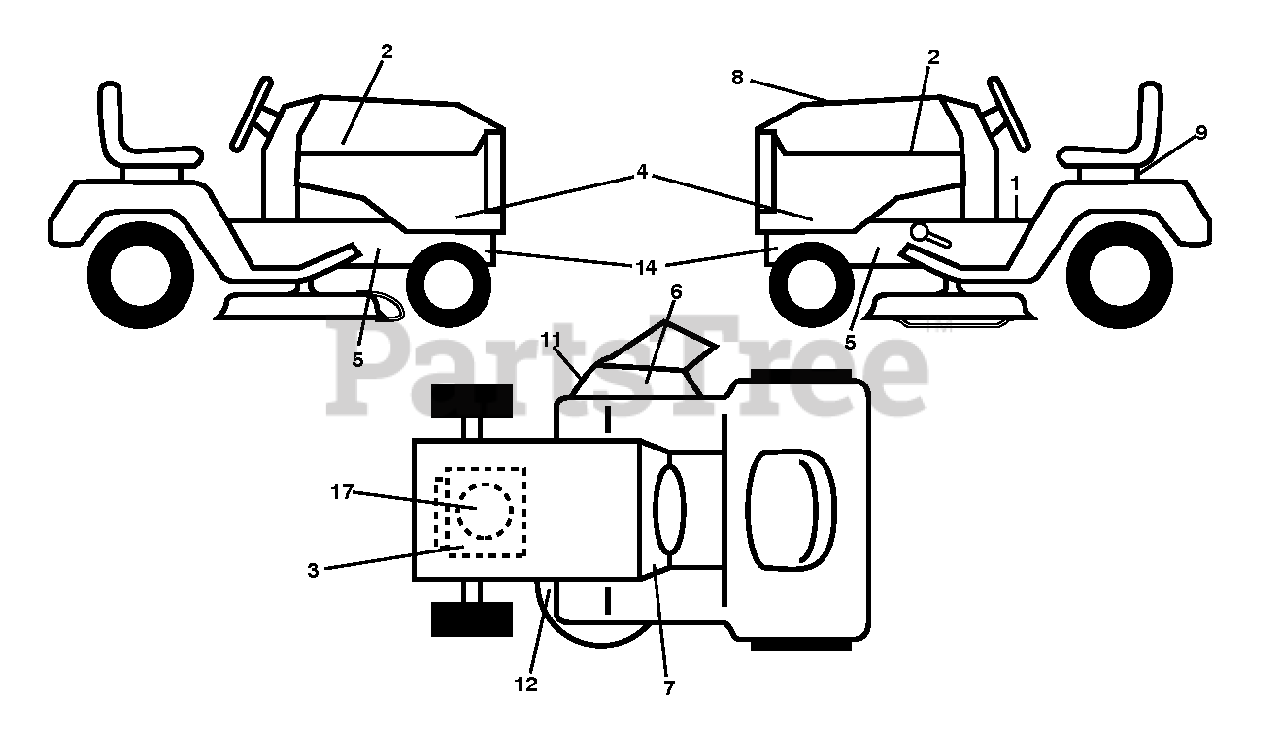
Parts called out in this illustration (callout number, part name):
1	DECAL TRACTOR SADDLE DECAL DEC
2	DECAL.BADGE.170MM.TEXTLOGO.
3	DECAL.ENGINE.WARNING
4	DECAL.SDPNL.HUSQLT.TC130
5	DECAL.CHASSIS.HOT.MUFFLER
6	DECAL, DECK DEFLECTOR, WARNING
7	DECAL.SNOWFLAKE.MS498.HUSQ
8	DECAL DECAL.RPL.BSM21.PB.TLW.3
9	DECAL BTRY SYMBOLS
11	DECAL.WARN.DFLCTR/CTFRG.SRD
12	DECAL.V.BELT.30"
14	DECAL.WARNING.SERVCE/FIRE
17	DECAL.ENG.BS.344CC.HS.382271
